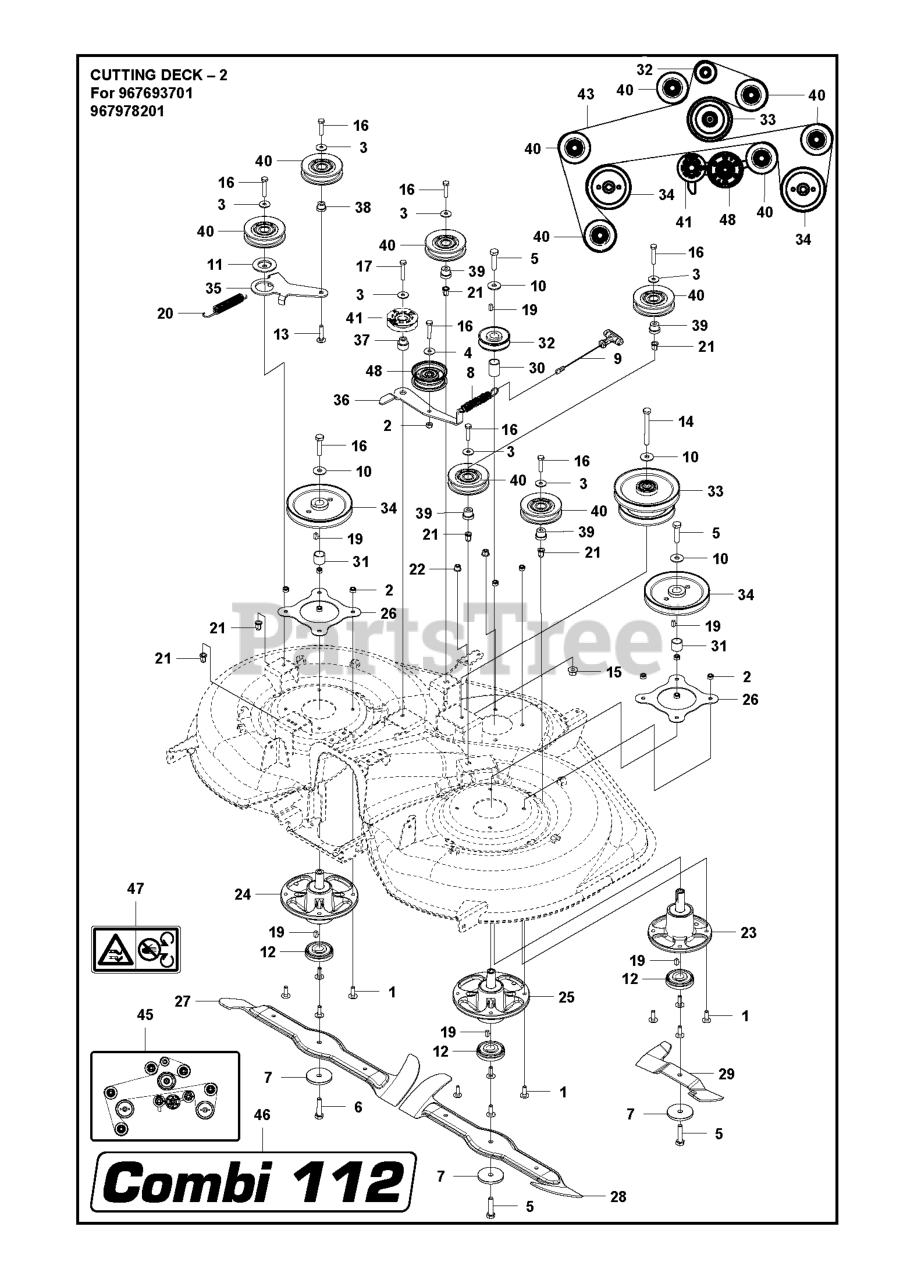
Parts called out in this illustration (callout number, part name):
2	LOCKNUT M8
13	Screw Mvbf 8 X 40
17	SCREW
21	BLIND RIVET NUT
22	NUT FLANGE
48	IDLER PULLEY
